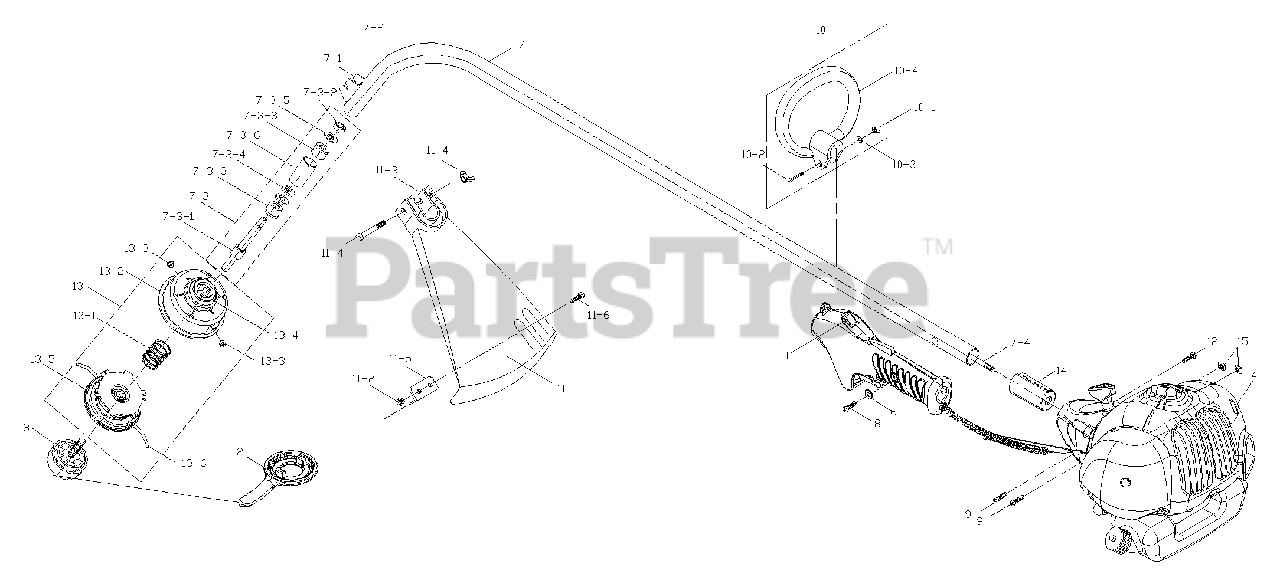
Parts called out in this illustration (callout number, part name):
1	STOP SWITCH
3	KNOB ASS'Y
4	ENGINE ASS'Y
7	SHAFT ASS'Y
7-3	CONNECTING HEAD ASS'Y
7-4	FLEX SHAFT
10	HANDLE ASS'Y
11	SHIELD ASS'Y
11-4	ADJUSTMENT
11-5	CONNECTOR
13	KIT,STRING HEAD
13-2	STRING BOX
13-4	KIT, CUTTING
13-5	INNER SPOOL
14	PRECAUTION COVER
